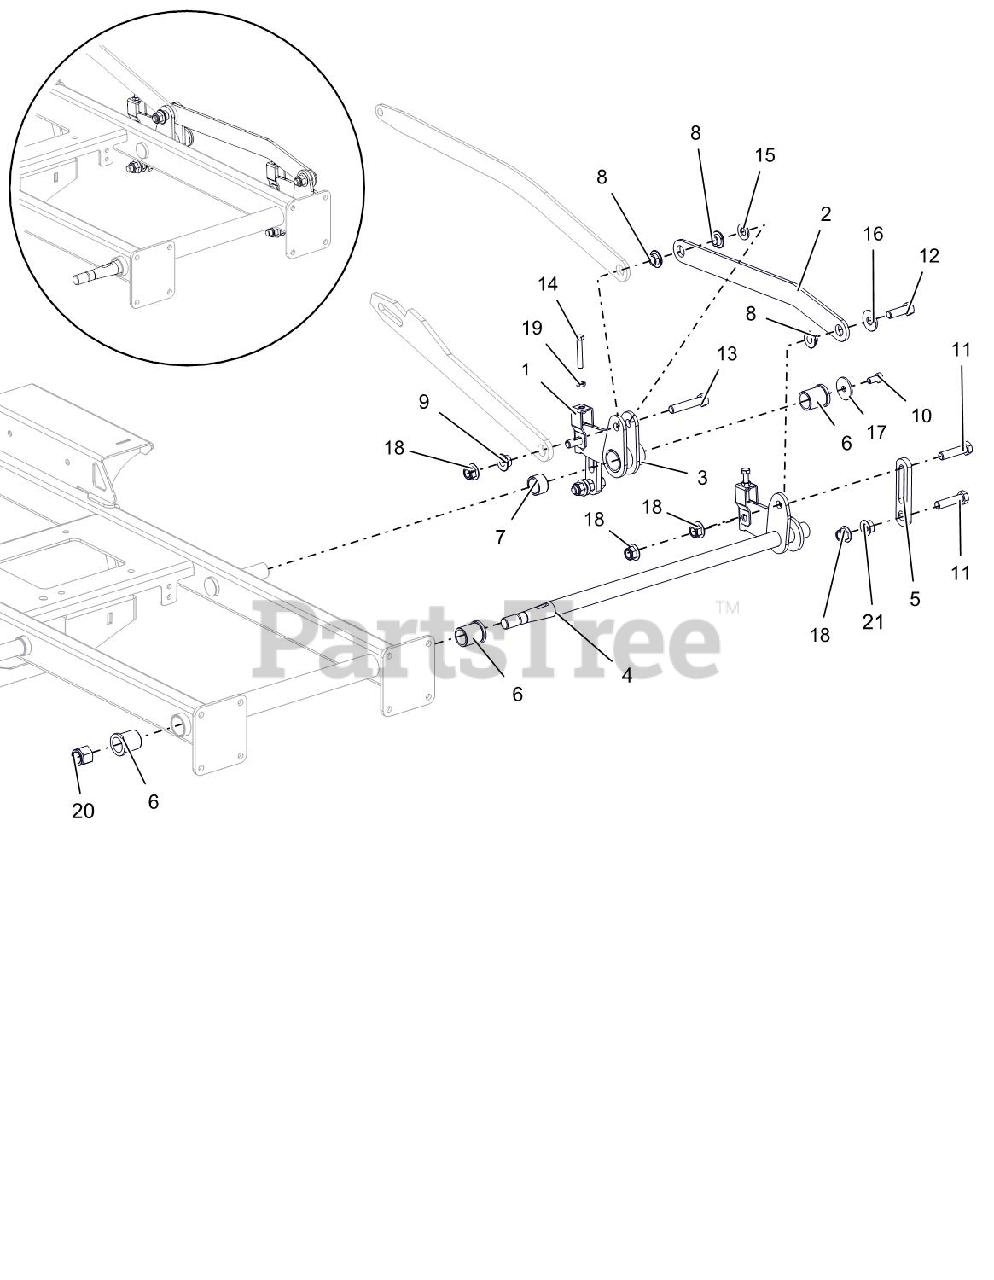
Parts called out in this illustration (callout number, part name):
1	BRKT, DECK LEVELING
2	PLATE, DECK ARM
3	WLDMT, REAR DECK ARM
4	WLDMT, FRONT LH DECK LIFT ARM
5	LINK-DECK LIFT - SHORT
6	BSHG-FLG 1.00X1.25X1.50X1.50
7	BUSH, SLV 1.00 X 1.25 X .75
8	BSHG, FLG .515X.750X.360X1.12
9	BSHG, FLG .515X.750X.480X1.12
10	@BLT-HEX .38-16X.75 GR5 YWZC
11	@BLT-HEX .50-13X2.00 GR5 YWZC
12	@BLT-HEX .50-13X1.50 GR5 YWZC
13	@BLT-HEX .50-13X2.50 GR5 YWZC
14	BLT-HEX .312-18X2.00 FTH GR5YZ
15	@WSHR-FL-STL.531X1.06X.095YWZC
16	@WSHR-FL-STL.563X1.38X.109YWZC
17	WSHR-FL-STL .380X1.50X.125YWZC
18	@NUT-LK-NYL-FLG .50-13 YWZC
19	NUT- JAM .312-18 YWZC
20	@NUT-LK-NYL .75-10 YWZC
21	NUT-SPNLK-FLG .50-13 YWZC
